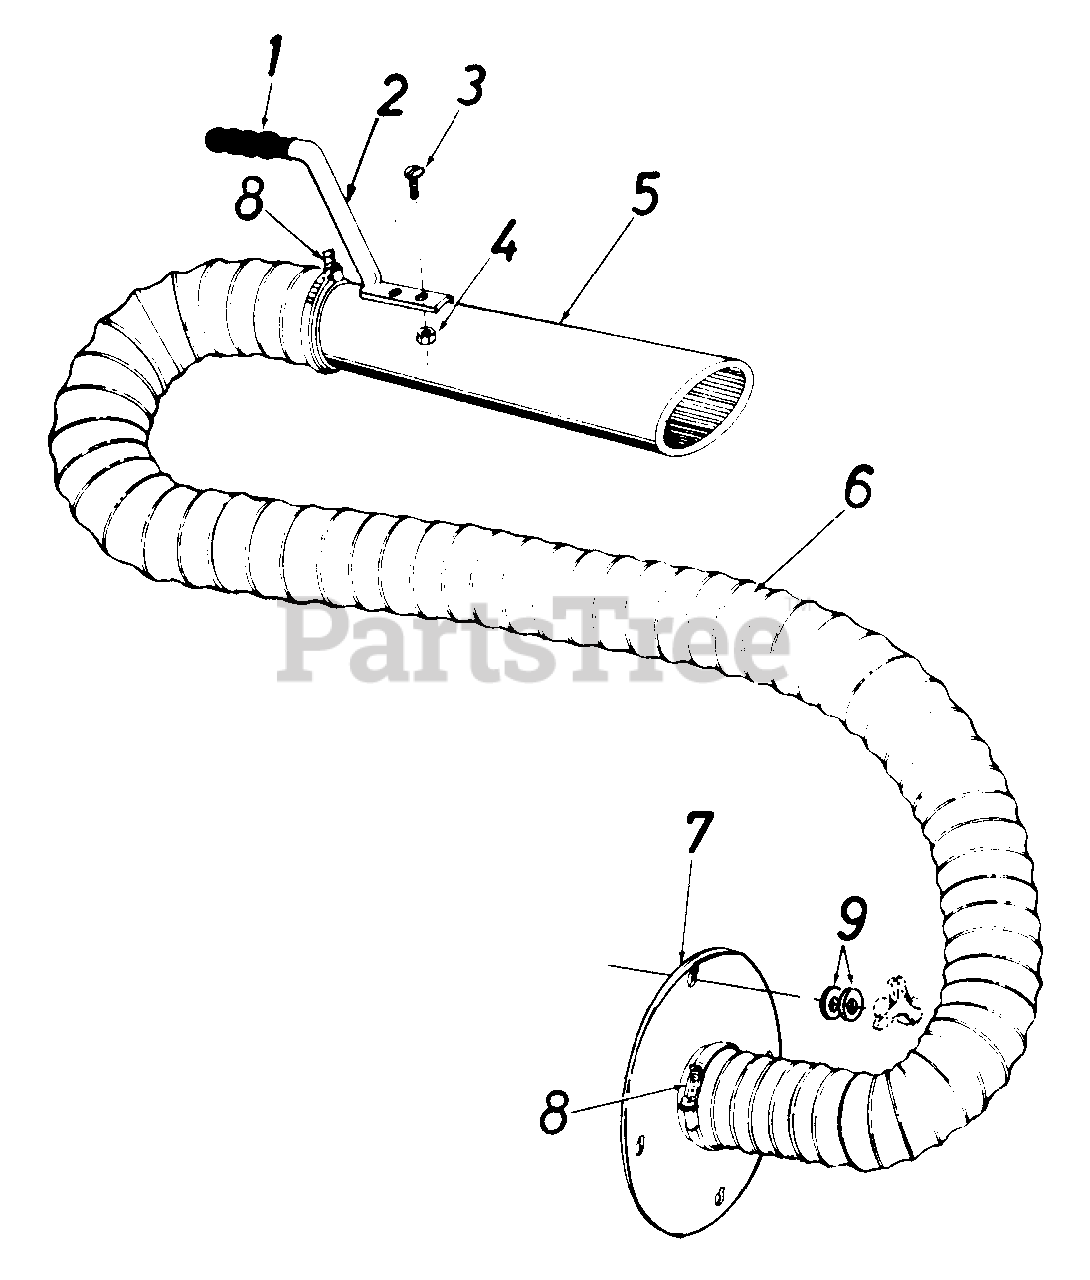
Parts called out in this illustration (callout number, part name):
1	GRIP-BLACK
2	HANDLE-HOSE NOZ LONG
3	SCREW-TRUSS SEMS #10-24 x .50
5	NOZZLE-HOSE
6	HOSE-4IN DIA x 10FT
9	WASHER-FL-.312 x 1.125 x .125
